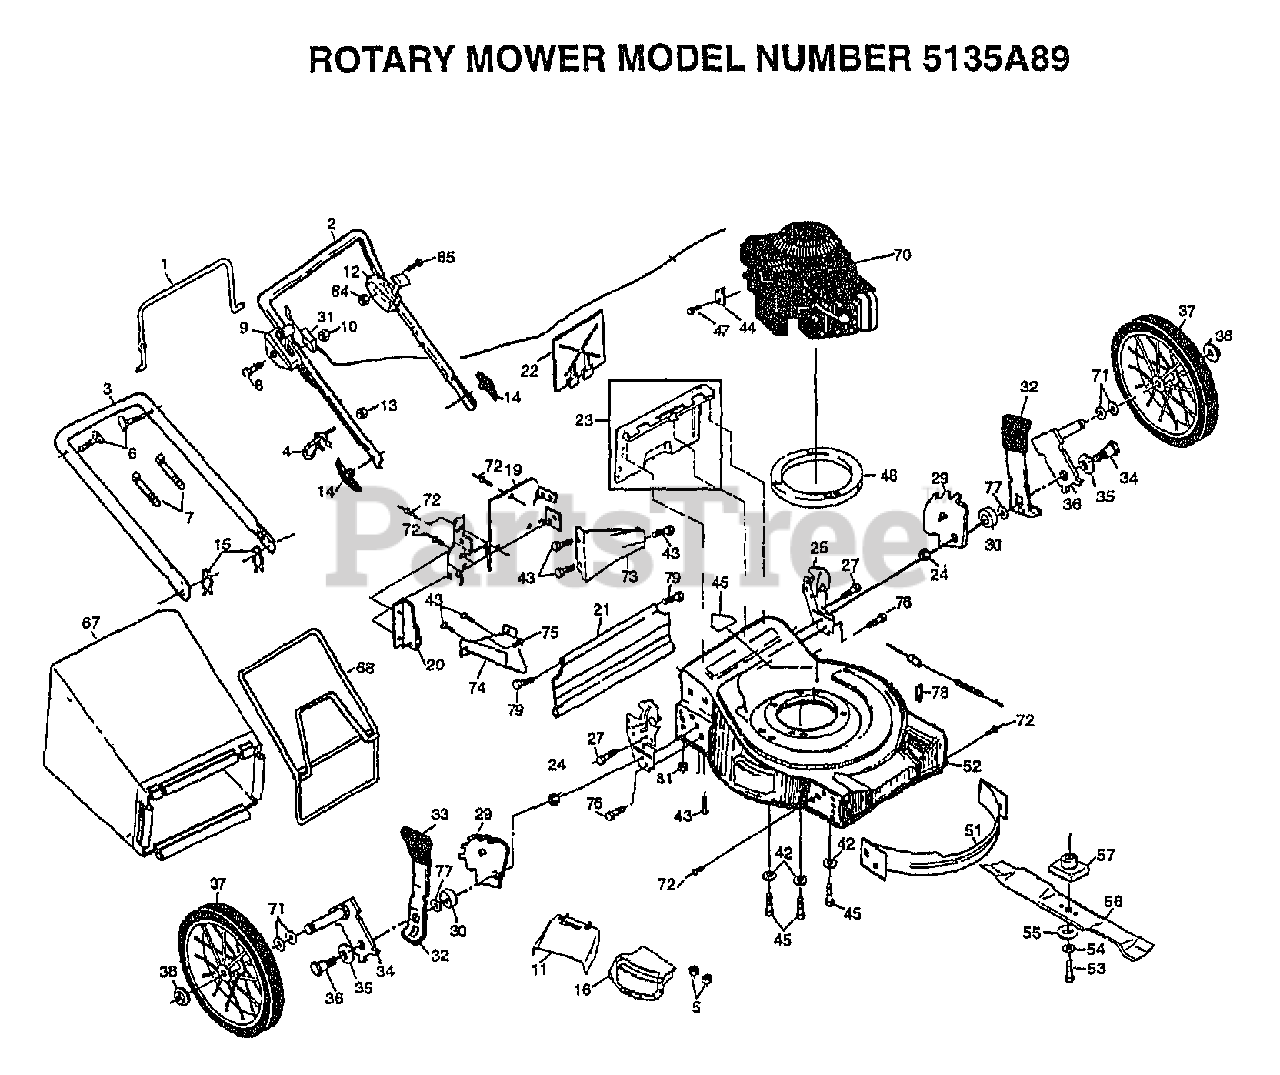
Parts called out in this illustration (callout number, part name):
1	BAIL.CNTRL.STD.BL
3	HANDLE LOWER
4	ROPE GUIDE
6	BOLT.HANDLE.LM
8	SCREW.HXHD.WASH.
9	"CONTROL, THROTTLE"
11	GUARD.DISCH.CLIPO
12	CONTROL.DRV.20FBD
14	"NUT,WING PM"
15	HAIRPIN COTTER
16	DOOR ASM.MULCHER
19	BACK PLATE
21	SKIRT.PUSH.20RD
22	MULCHER PLATE
23	KIT.DOOR.RR.20STL
24	LOCKNUT PM
25	HDLE BRKT ASSY LH
26	HDLE BRKT ASSY RH
27	SCREW.HXWS.5/16
29	BRKT.WHL.ADJ
30	SPACER.HEIGHT.ADJ
31	"CABLE,ENG ZONE CO"
32	SPRING SELECTOR
33	KNOB PM
34	"AXLE ARM,REAR PM"
36	BOLT SHLD 3/8-16
37	WHELL ASM 14X2RAD
38	HEX FLANGE LOCKNT
43	SCREW
44	CABLE CLAMP
45	SCREW
46	DECAL-DANGER PM
47	SCREW PM
48	ENGINE SPACER
51	KIT.BAF.FRT.20RD
52	KIT.HOUSING.20RD.FWBD.RED
53	SCREW
54	LOCKWASHER
55	"WASHER,HARDEN"
56	BLADE.20.MULCH.AY
57	ADAPTOR.BLADE.LM
67	GRASSBAG.250B1.BL
68	FRAME.CATCHER.2.5
71	WAVE WASHER
72	BLIND RIVET
73	REAR BAFFLE
74	DISCHARGE GUARD
75	SCREW.HXTAP.10-24
77	WASHER PM
78	GUIDE.CABLE.FWBD
79	HINGE SCREW
81	LOCKNUT PM
84	PAN HEAD SCREW
85	LOCKNUT
